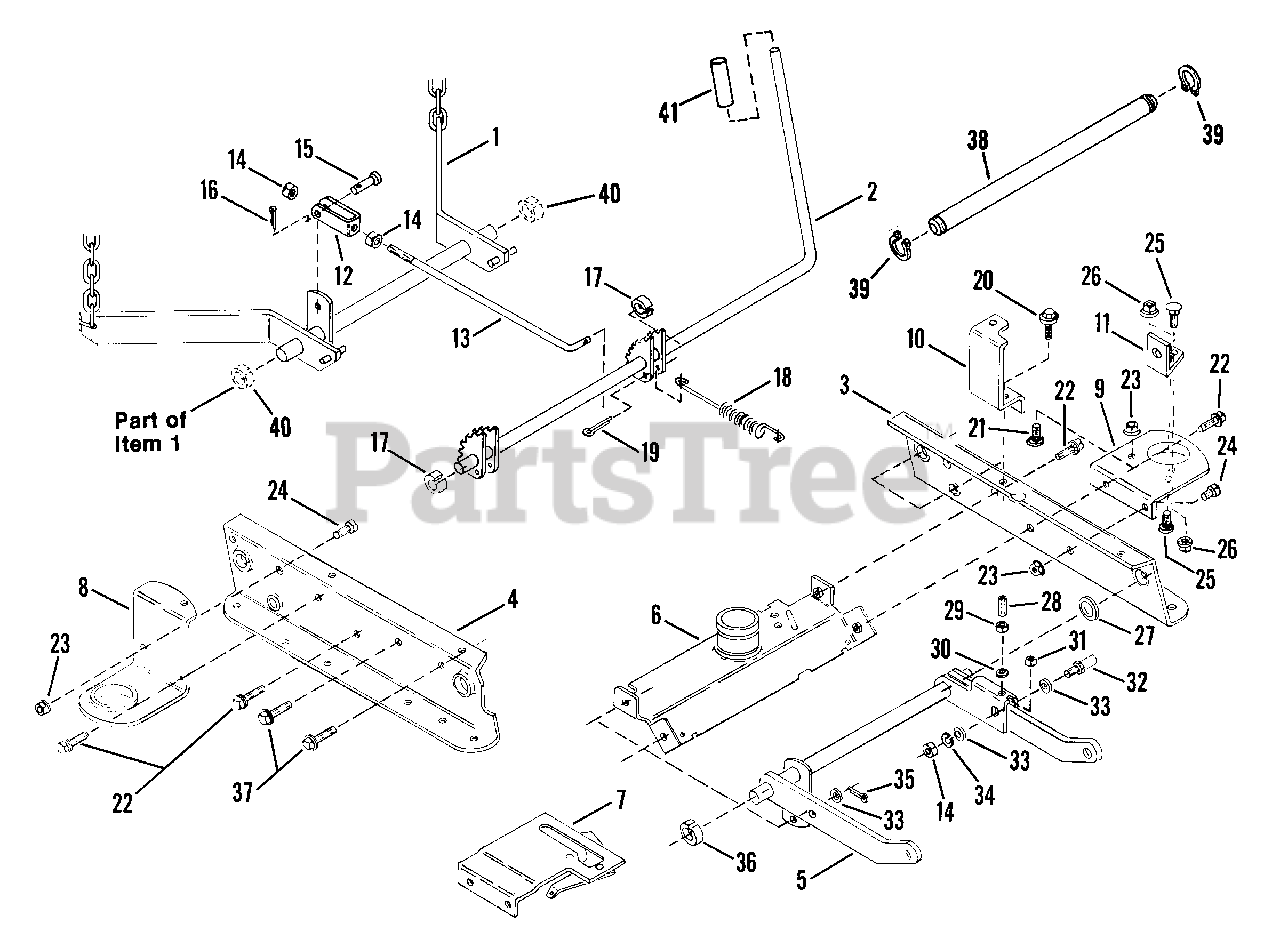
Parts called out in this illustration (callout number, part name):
1	ASSEMBLY, Rear Lift Arm
2	LIFT LEVER STRUCTURE
3	RAIL, Left Half
4	RAIL, Right Half
5	STRUCTURE, Front Lift Arm
6	BRACE, Weldment
7	ASSEMBLY, Clutch Plate
8	SPINDLE, Brace Right Half
9	SPINDLE, Brace Left Half
10	BRACKET, Cover
11	ANCHOR
12	CLEVIS, Timing Rod
13	ROD, Timing
14	NUT, Hex 3/8-24
15	PIN, 3/8 x 1 1/16" Clevis
16	PIN, Cotter 3/32x3/4
17	RING, White
18	SPRING, (CAM-LIFT)
19	PIN, Cotter 5/32x1
20	SCREW, Self-Tapping 1/4-20x5/8
21	SCREW, Cap-Hex Head 3/8-24x1
22	SCREW, Hex Washer Self-Tapping 3/8-16x1
23	NUT, Lock 3/8-24
24	SCREW, Cap-Hex Head 3/8-24x3/4
25	BOLT, Carriage 5/16-18x3/4
26	NUT, Hex Flange Lock 5/16x18
27	WASHER, (Spacer)
28	SCREW, Set-Hex Socket 5/16-18x1 1/4
29	NUT, Jam-Hex 5/16-18
30	WASHER, SAE 5/16-18
31	NUT, Hex 5/16-18
32	PIN, Shoulder Bolt
33	WASHER, 3/8
34	WASHER, Lock 3/8
35	PIN, Cotter 1/8x3/4
36	RING, Red
37	SCREW, Hex Washer Self-Tapping 5/16-18x5/8
38	SUPPORT, Rod
39	RING, 5/8" External Retaining
40	RING, Blue
41	GRIP, Height Adjustment Lever
